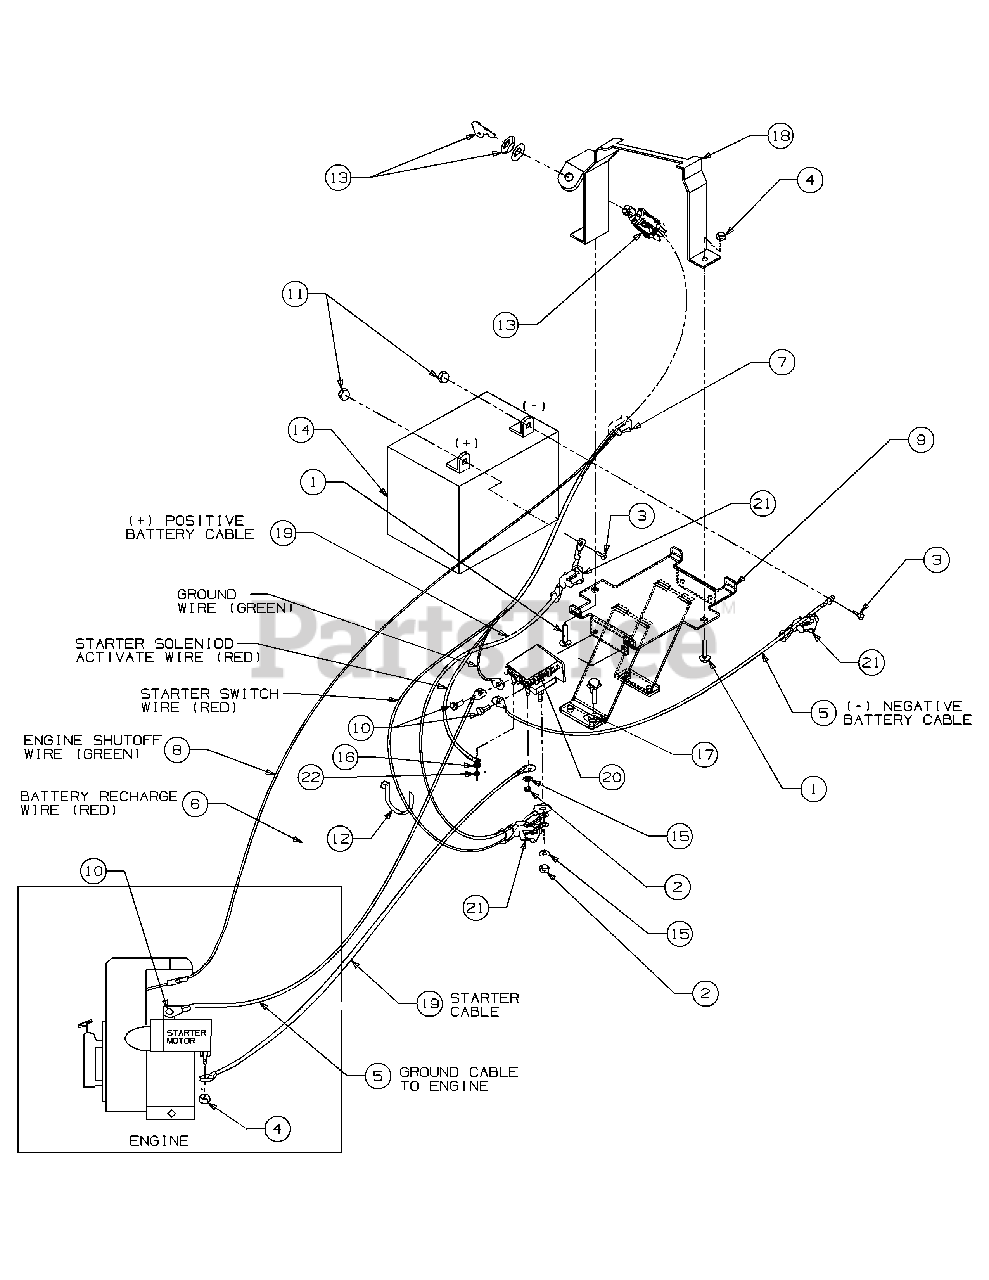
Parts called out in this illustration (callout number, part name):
1	Carriage Screw, 1/4-20 x 1.25
2	Hex Nut, 5/16-24
3	Flange Screw, 1/4-20 x .625
4	Hex Locknut, 1/4-20
5	Cable (ground wire to starter motor bracket)
7	Wire Harness Assy. (available as complete assembly only).
8	Ground Wire Assy. (shut off)
11	Hex Nut, 1/4-20
12	Cable Tie
13	Ignition Switch
14	Battery, 270 CCA
15	Lock Washer
16	Lock Washer, #10
17	External Lock Washer 5/16
18	Keyswitch Clamp
19	Cable (solenoid to starter motor)
20	Solenoid (Incl. nuts and washers for cables and wires)
21	Boot, Insulating
22	Locknut, #10-32
